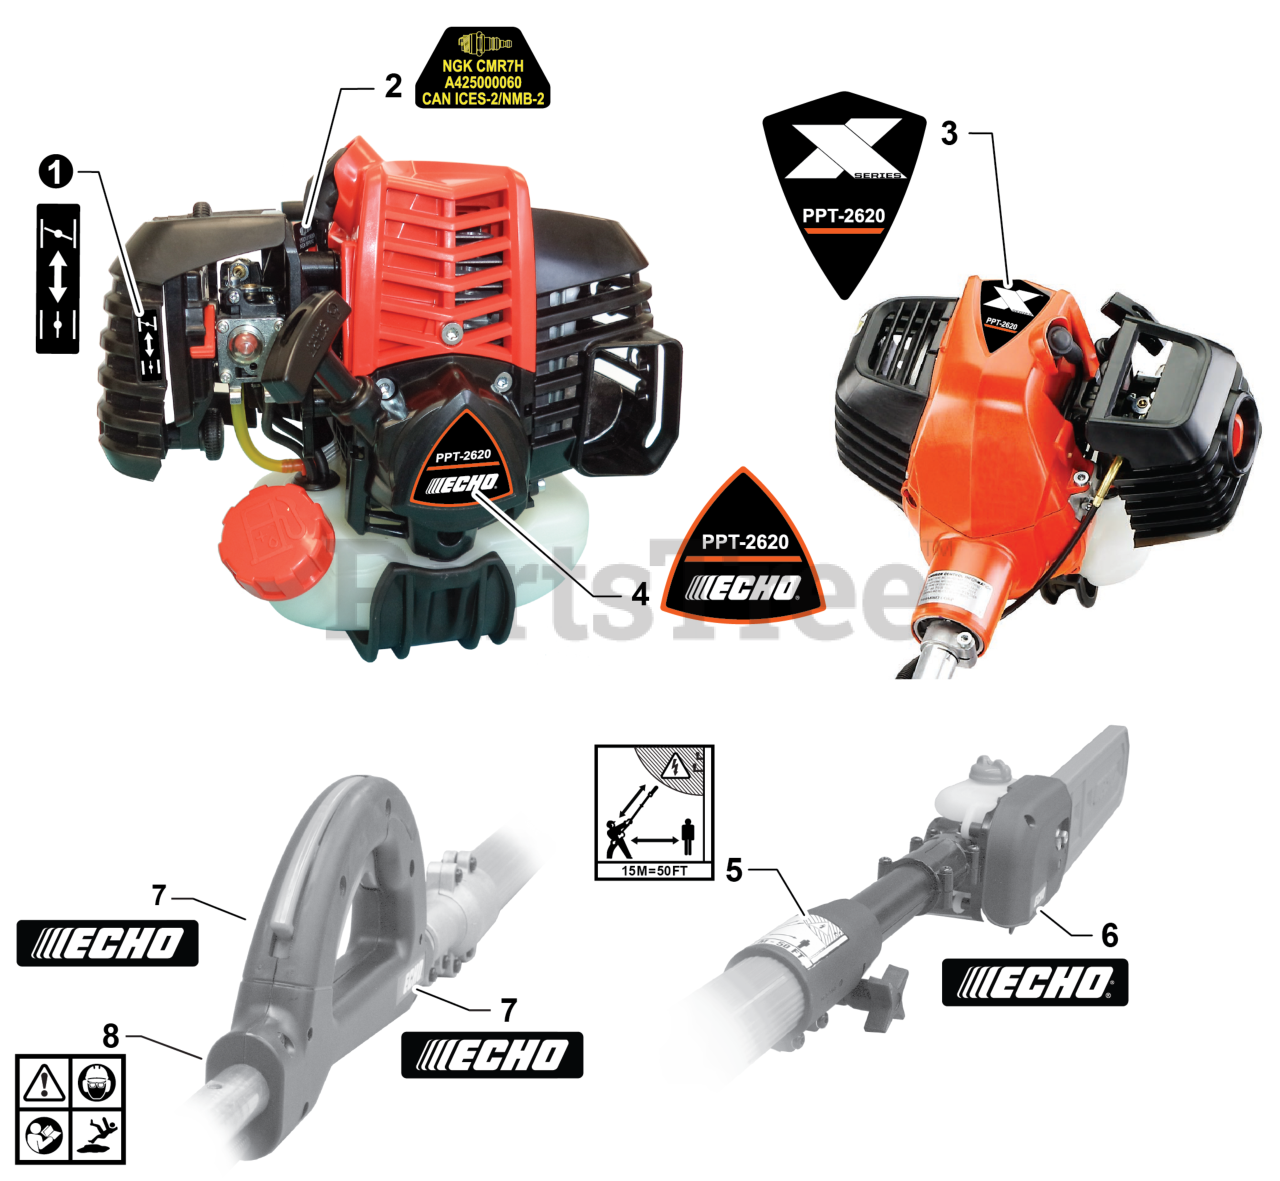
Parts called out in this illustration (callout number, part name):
1	LABEL - CHOKE
2	LABEL - SPARK PLUG - CMR7H
3	LABEL - MODEL PPT-2620
4	LABEL - RECOIL STARTER - PPT-2620
5	LABEL - CAUTION
6	LABEL - ECHO
7	LABEL - ECHO
8	LABEL - CAUTION
